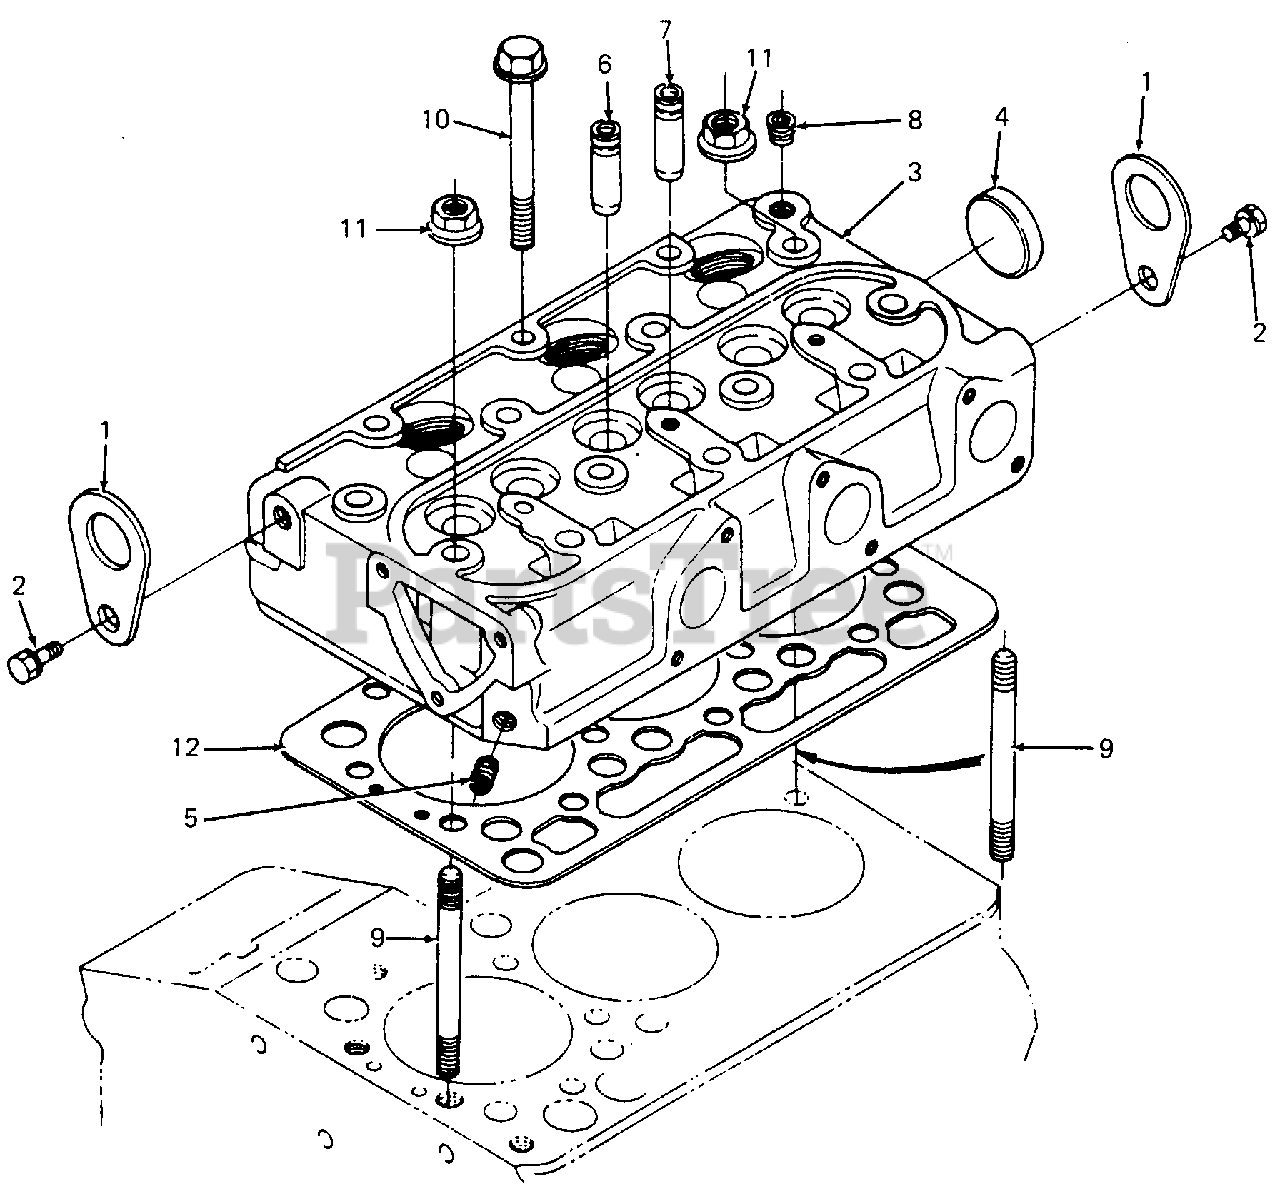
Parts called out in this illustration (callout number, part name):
2	Screw, Hex Cap
3	Head Assy, Cylinder
6	Guide, Intake Valve
7	Guide, Exhaust Valve
8	Plug
12	Gasket, Head
